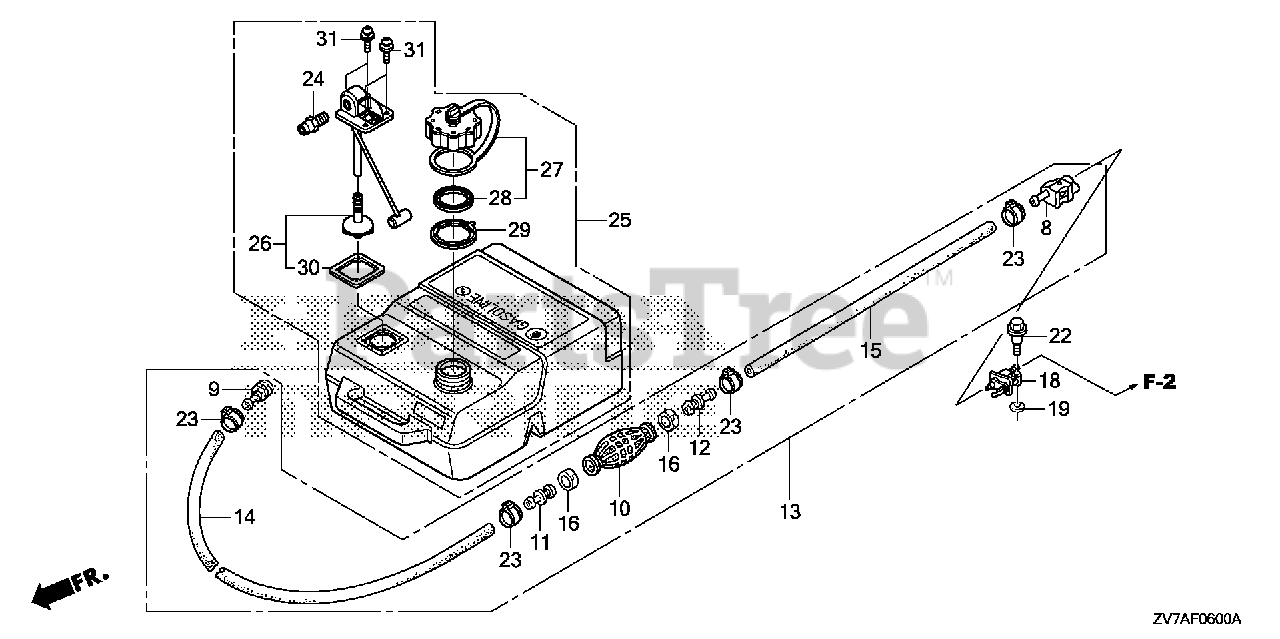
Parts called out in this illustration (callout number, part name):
8	CONNECTOR ASSY., FUEL (A)
9	CONNECTOR, FUEL
10	BULB, PRIMER
11	VALVE, IN.
12	VALVE, OUTLET
13	TUBE ASSY., FUEL TANK
14	TUBE, FUEL LONG (7.3X2000)
15	TUBE, FUEL SHORT
16	BAND, TUBE CLIP (20MM)
18	CONNECTOR ASSY., FUEL (B)
19	WASHER, PIVOT
22	BOLT, SPECIAL (6X22) (CT200)
23	CLAMP, FUEL TUBE (14.0)
24	FITTING, QUICK DISCONNECT
25	TANK ASSY., FUEL
26	FILTER KIT, FUEL
27	CAP, FUEL FILLER
28	GASKET, FUEL CAP
29	RETAINER, PRESSURE RELIEF
30	GASKET, FUEL PICK-UP
31	BOLT-WASHER (5MM) (SEAL)
